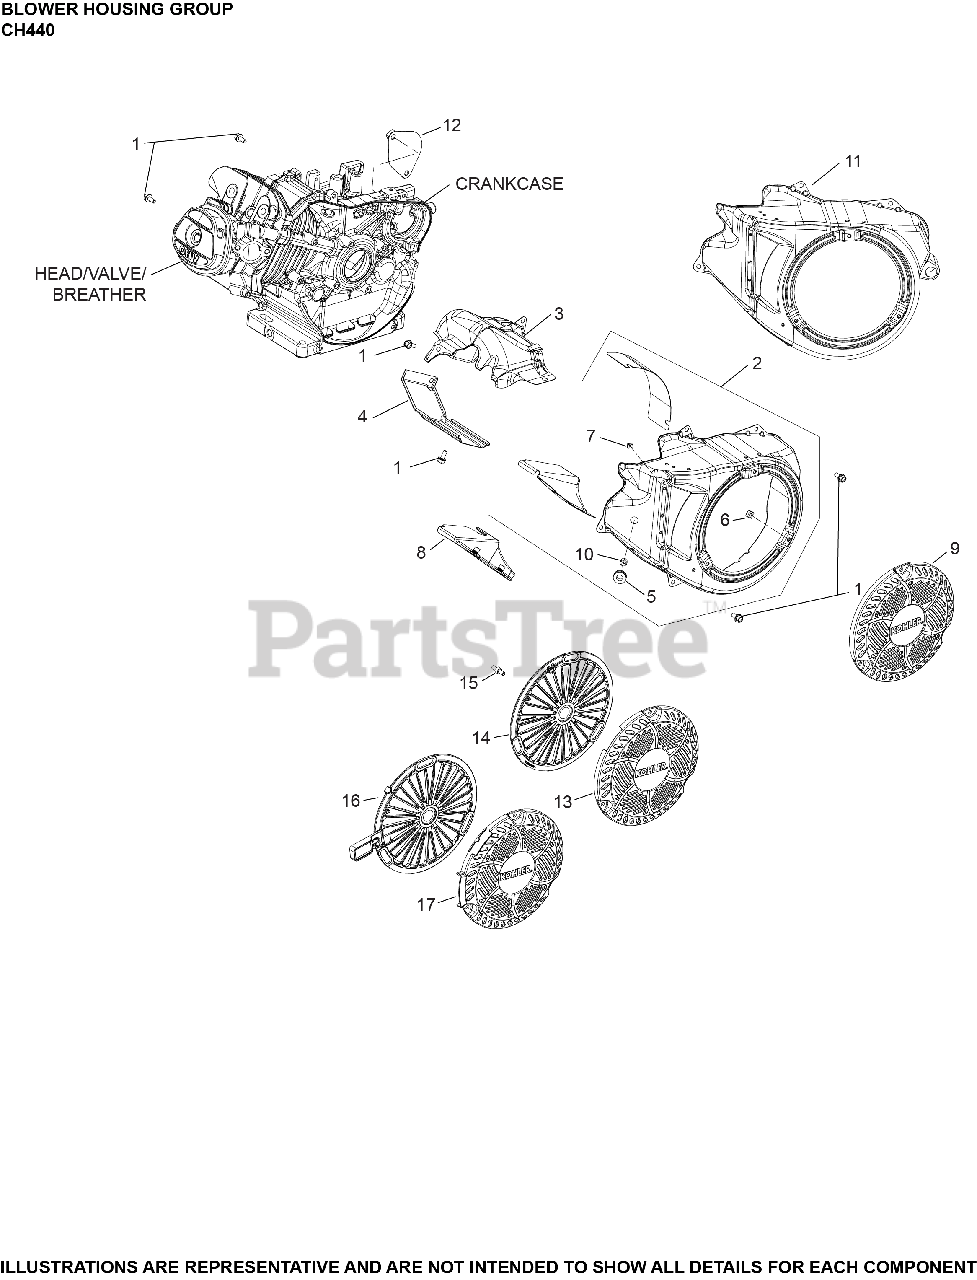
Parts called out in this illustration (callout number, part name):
1	SCREW, HEX FLANGE (M6)-USE 25 086 433-S
2	HOUSING, BLOWER ASSEMBLY
3	SHIELD, UPPER HEAT
4	SHIELD, CYLINDER HEAD
5	ISOLATOR, VIBRATION
